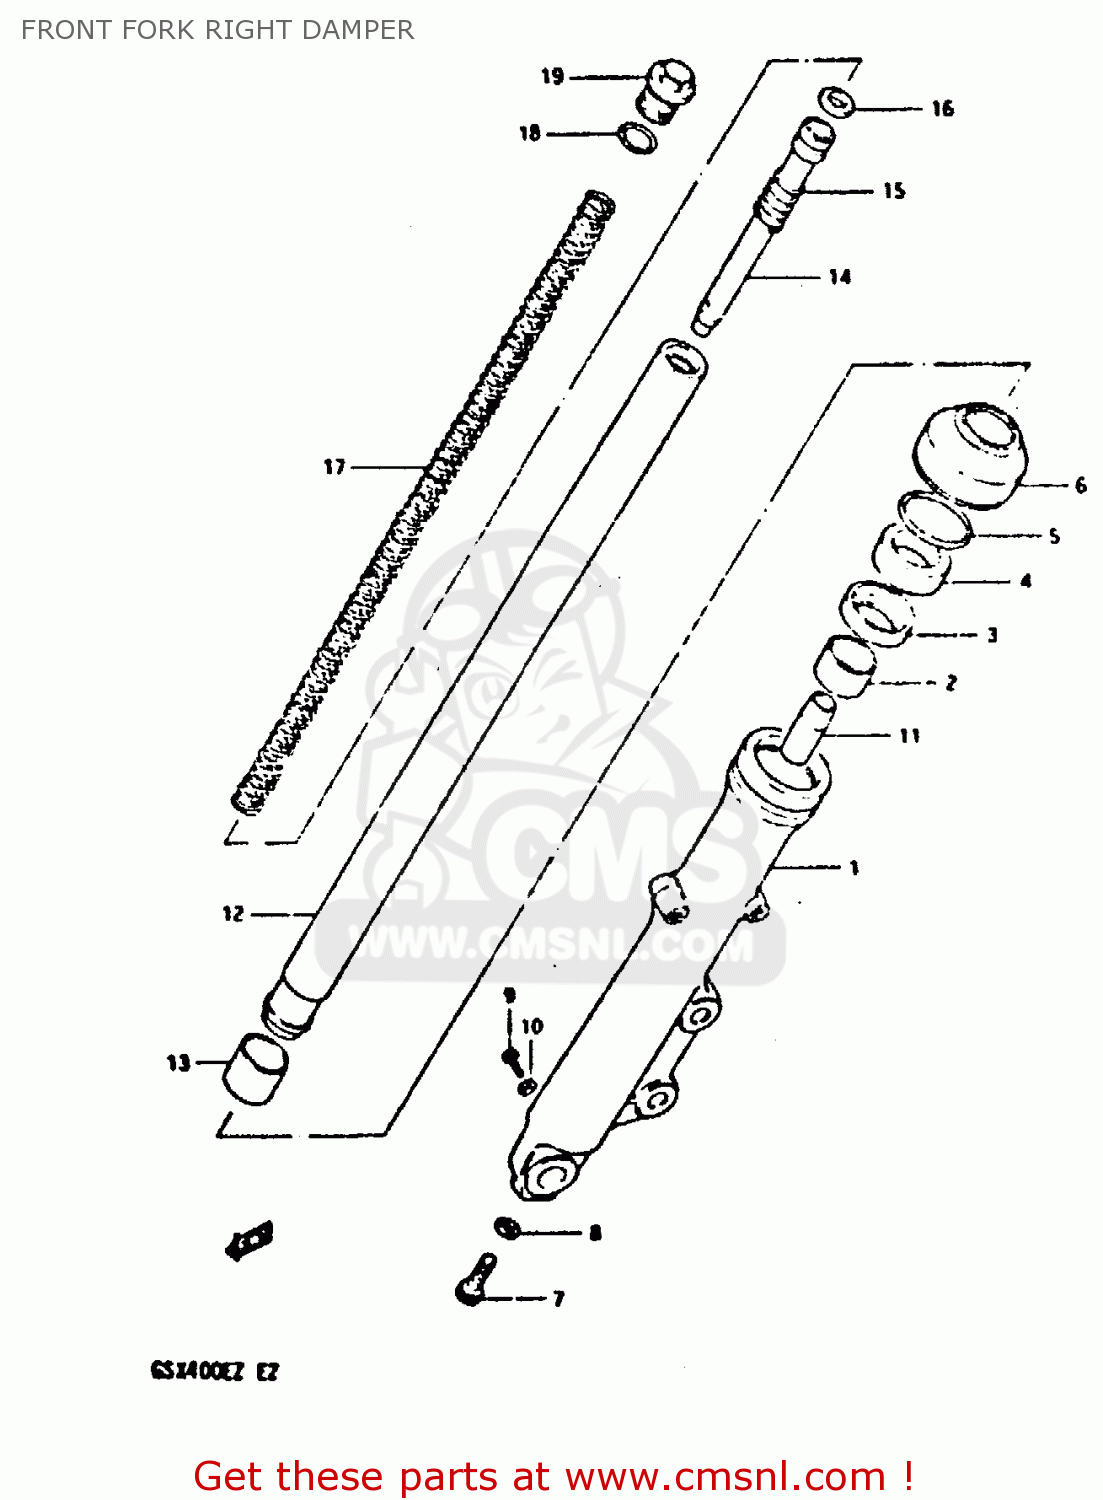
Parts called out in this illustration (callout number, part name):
1	OUTER TUBE RH
2	BUSH,GUIDE
3	SPACER,OIL SEAL
4	OIL SEAL,FRONT FORK
5	CIRCLIP,FORK OIL SEAL
6	DUST SEAL
7	BOLT(8X27)
8	GASKET (NAS)
9	BOLT
10	GASKET,DRAIN,PLUG (NAS)
11	PIECE,OIL LOCK
12	TUBE,INNER
13	BUSH
14	CYLINDER,FRONT FORK
15	SPRING,REBOUND
16	RING,PISTON
17	SPRING,FR.FORK
18	O RING
19	BOLT
